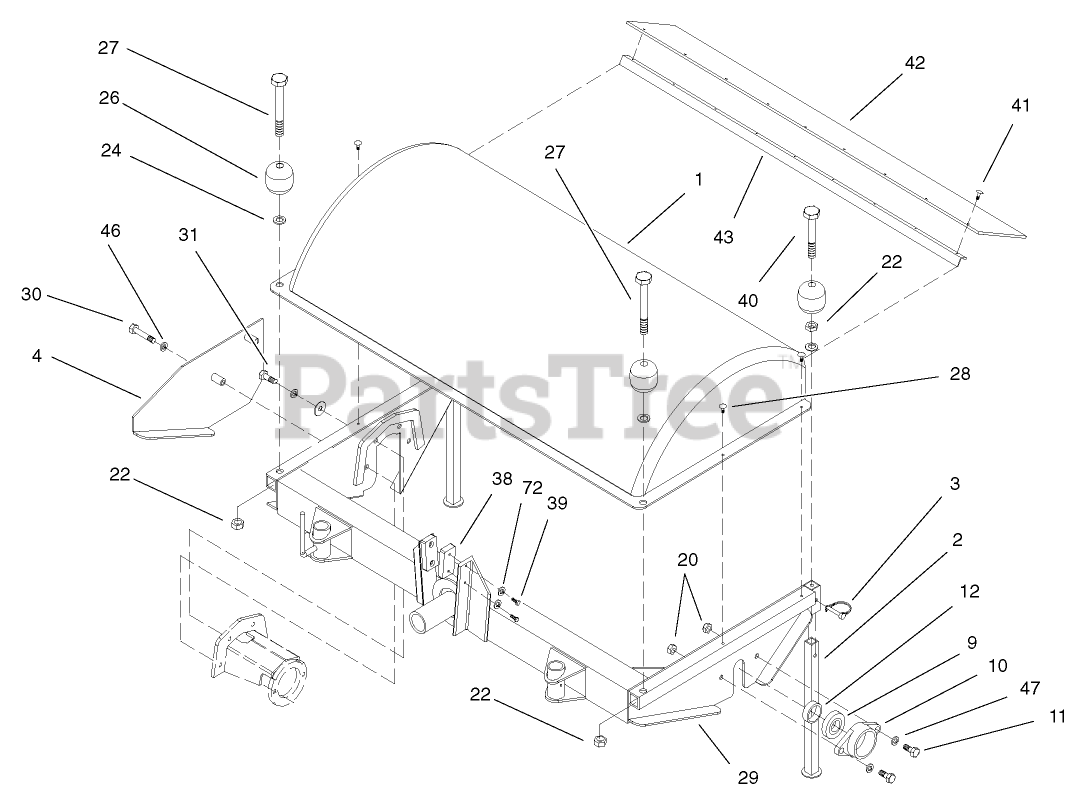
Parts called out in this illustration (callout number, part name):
1	COVER-BROOM
2	STAND-HEAD, BROOM
3	PIN-LYNCH
4	PLATE-GUARD, MOTOR
9	BEARING
10	HOUSING-BEARING
11	SCREW-HH
12	COLLAR-LOCKING
20	NUT-HEX
22	NUT-JAM
24	WASHER
26	ROLLER
27	SCREW-HH
28	SCREW
29	BROOM HEAD FRAME ASM, WL
30	SCREW-HH
31	SCREW-HH
38	BUMPER-RUBBER
39	SCREW-HH
40	SCREW-HH
41	RIVET-POP
42	BELTING-RUBBER
43	PLATE-MOUNT, GUARD
46	WASHER-LOCK
47	WASHER-FLAT
72	WASHER-LOCK
